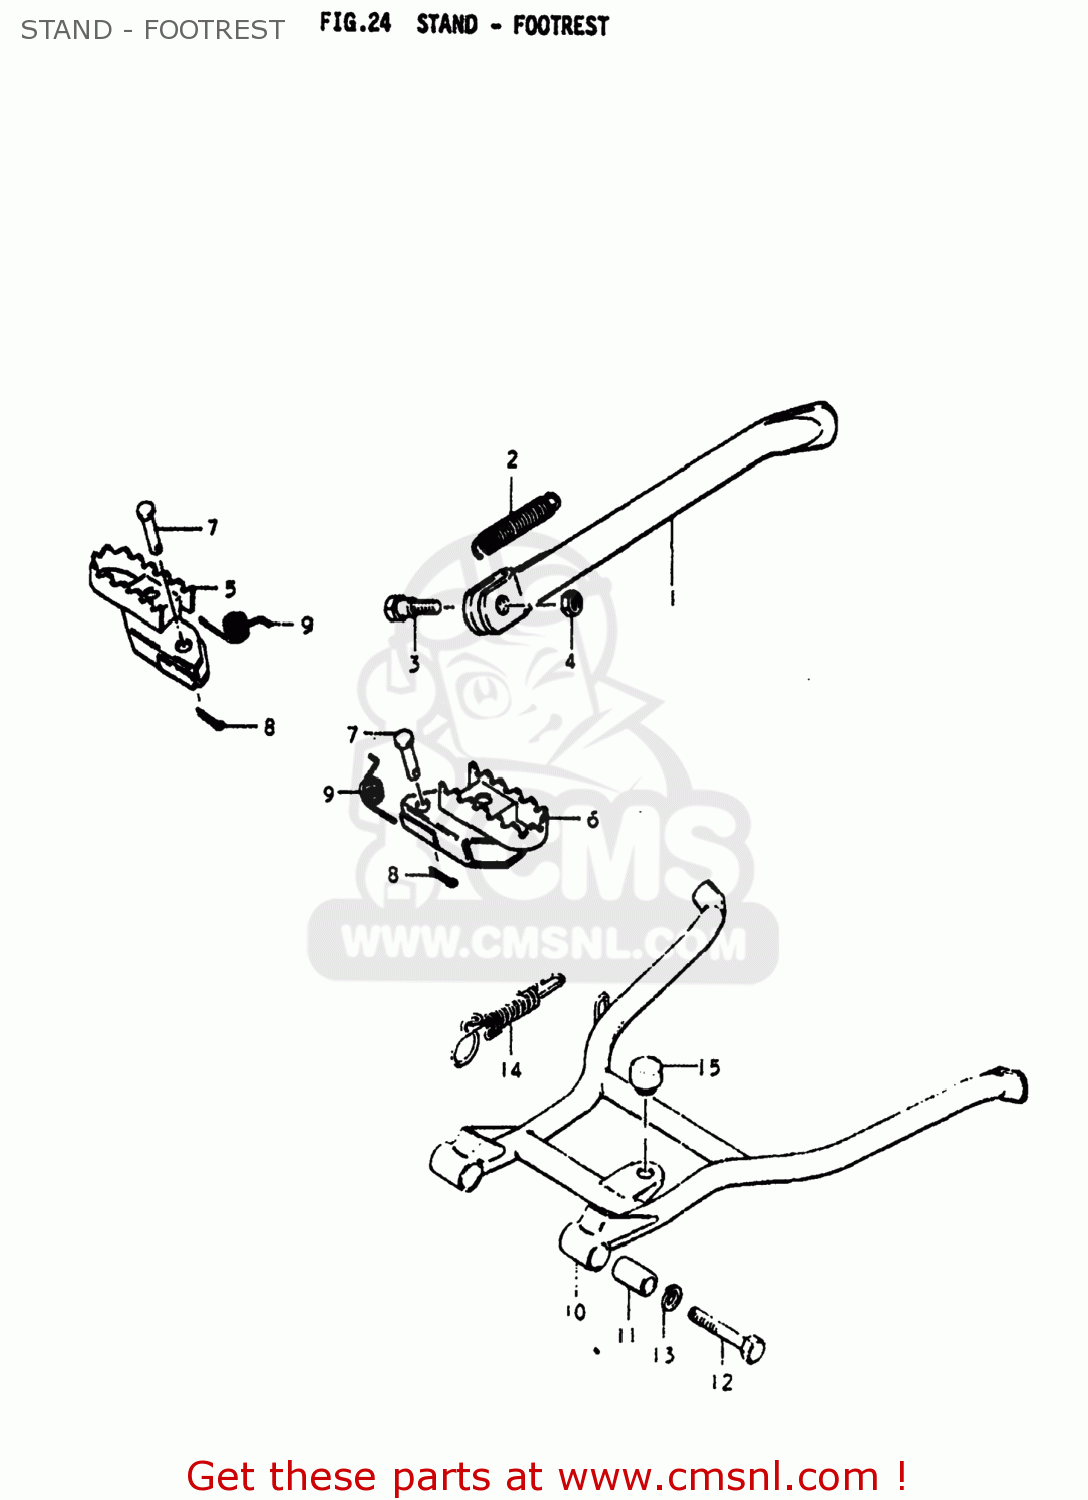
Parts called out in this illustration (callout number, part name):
1	STAND,SIDE
2	SPRING
3	BOLT(10X30)
4	NUT
5	FOOTREST,FRONT
6	FOOTREST
7	PIN
8	PIN 25X20
9	SPRING
10	STAND,CENTER
11	SPACER(10.5X16X30)
12	BOLT (10X50)
13	LOCK WASHER
15	CUSHION(11.5X22X20)
